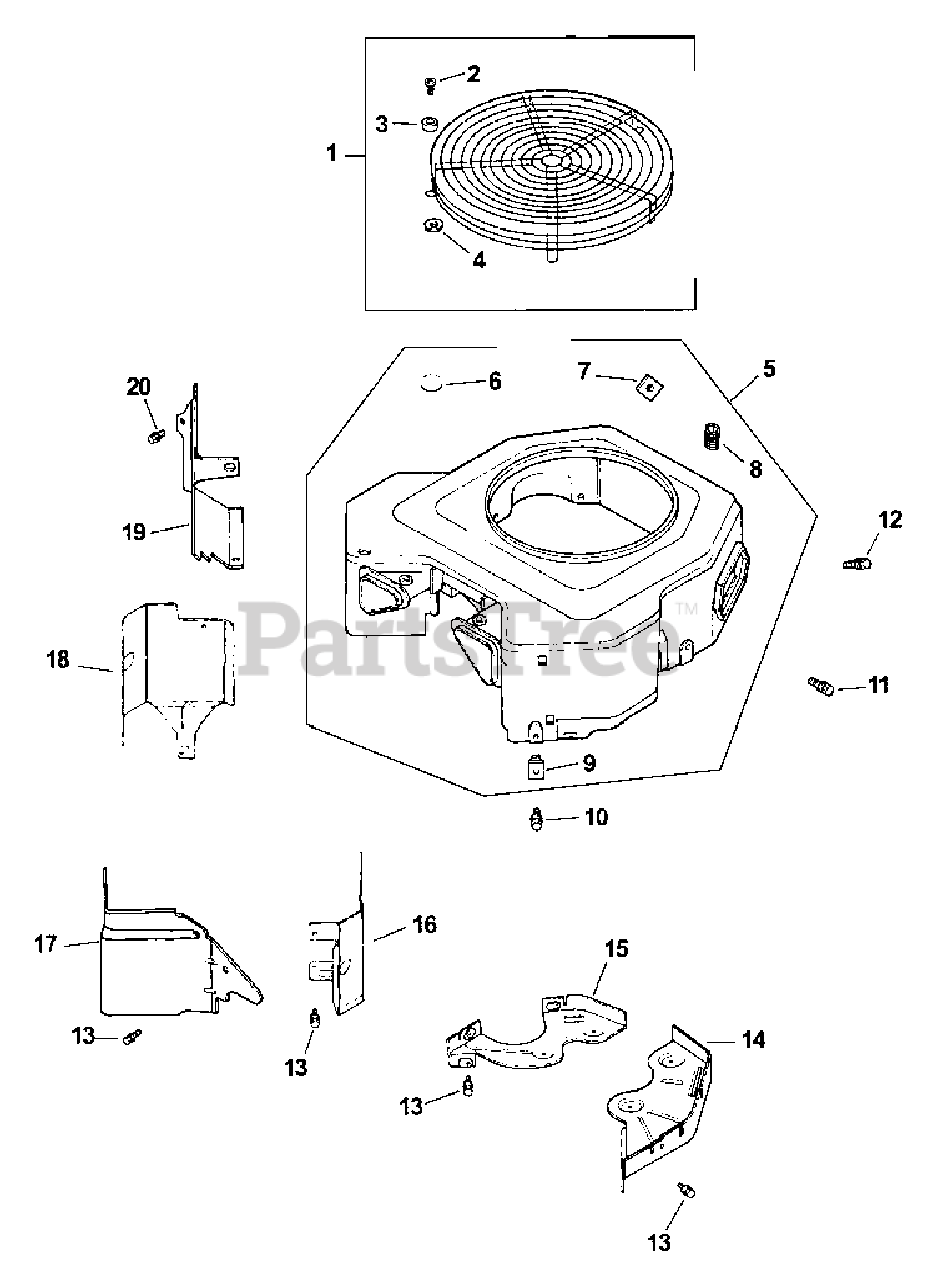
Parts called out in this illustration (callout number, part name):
2	Pan Head Screw
3	Spacer
5	Blower Housing
6	Button Plug (9/16")
7	Plastic Nut
9	Plastic Nut
10	Hex Flange Screw (M5 x .8 x 20)
11	Hex Flange Screw (M5 x .8 x 16)
12	Hex Flange Screw (M5 x .8 x 16)
13	Hex Flange Screw (M6 x 1.0 x 16)
14	Backing Plate #2 Side
15	Backing Plate #1 Side
16	Cylinder Barrel Baffle # 2 Side
17	Valley Baffle # 2 Side
18	Cylinder Barrel Baffle # 1 Side
19	Valley Baffle # 1 Side
20	Hex Flange Screw (M5 x .8 x 10)
